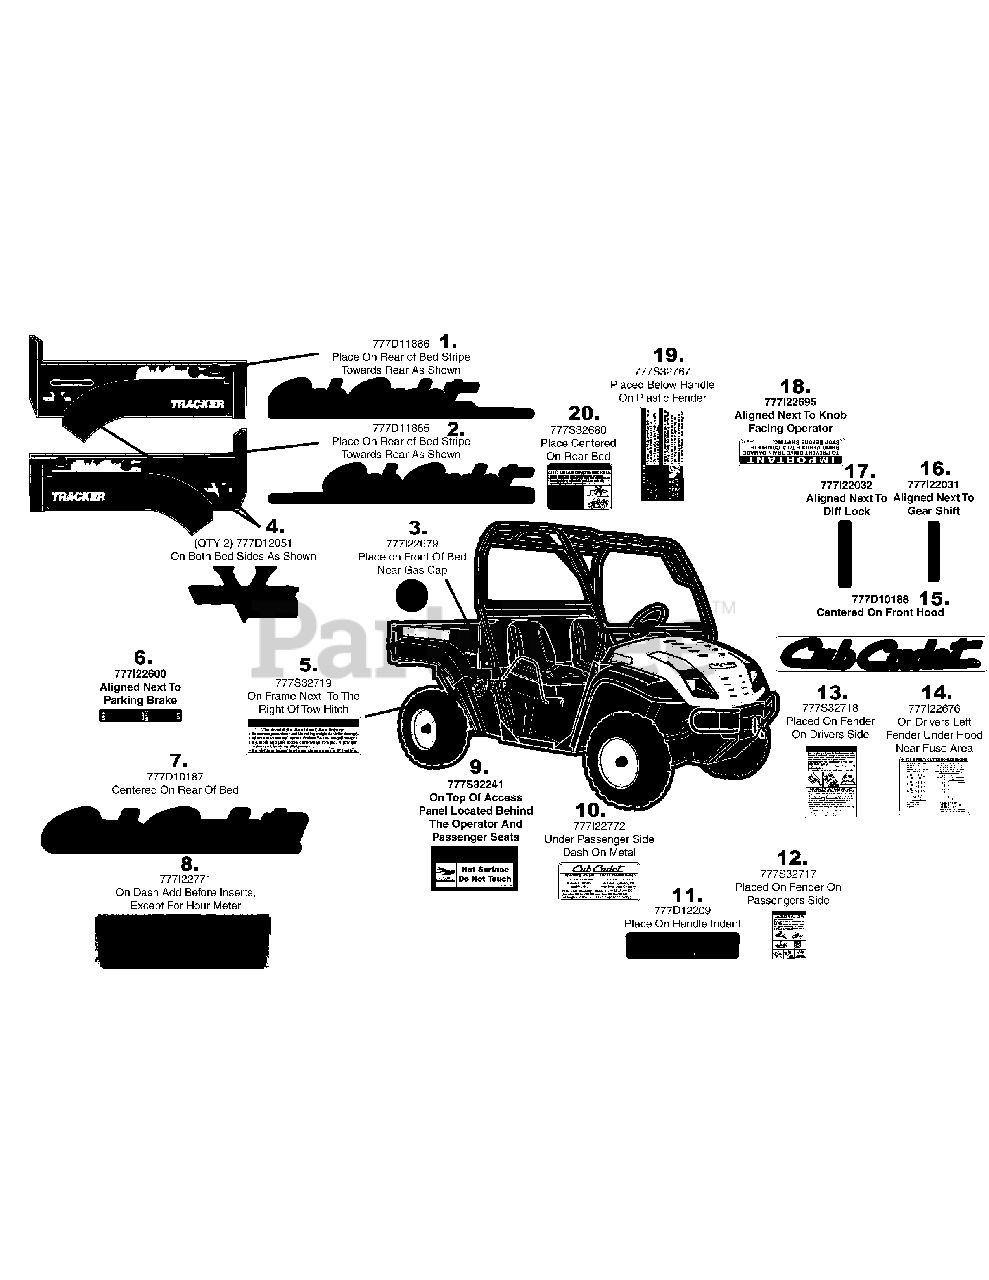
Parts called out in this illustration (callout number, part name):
1	LABEL-UV CUB CAMO EURO LEFT
2	LABEL-UV CUB CAMO EURO RIGHT
3	LABEL-CHECK ENG OIL
4	LABEL-UV VOL OLIVE GREEN 624
5	LABEL-TOW HITCH
6	LABEL-PARK BRAKE
7	LABEL-CUB CADET BED
8	LABEL-DASH PANEL
9	LABEL-HOT SURFACE
10	LABEL-CUB UV INFO
11	LABEL-UV DASH LOGO CAMO
12	LABEL-RIDER FALL RH FENDER
13	LABEL-ROLL & FALL LH FENDER
14	LABEL:UV:4X4 KOHLER FUSE
15	LABEL-CUB CADET HOOD
16	LABEL-FWD/REV SHIF
17	LABEL-DIFF LOCK CO
18	LABEL:4X4 SHIFT
19	LABEL-4X4 CARGO BOX HANDLE
20	LABEL-CARGO LOAD
